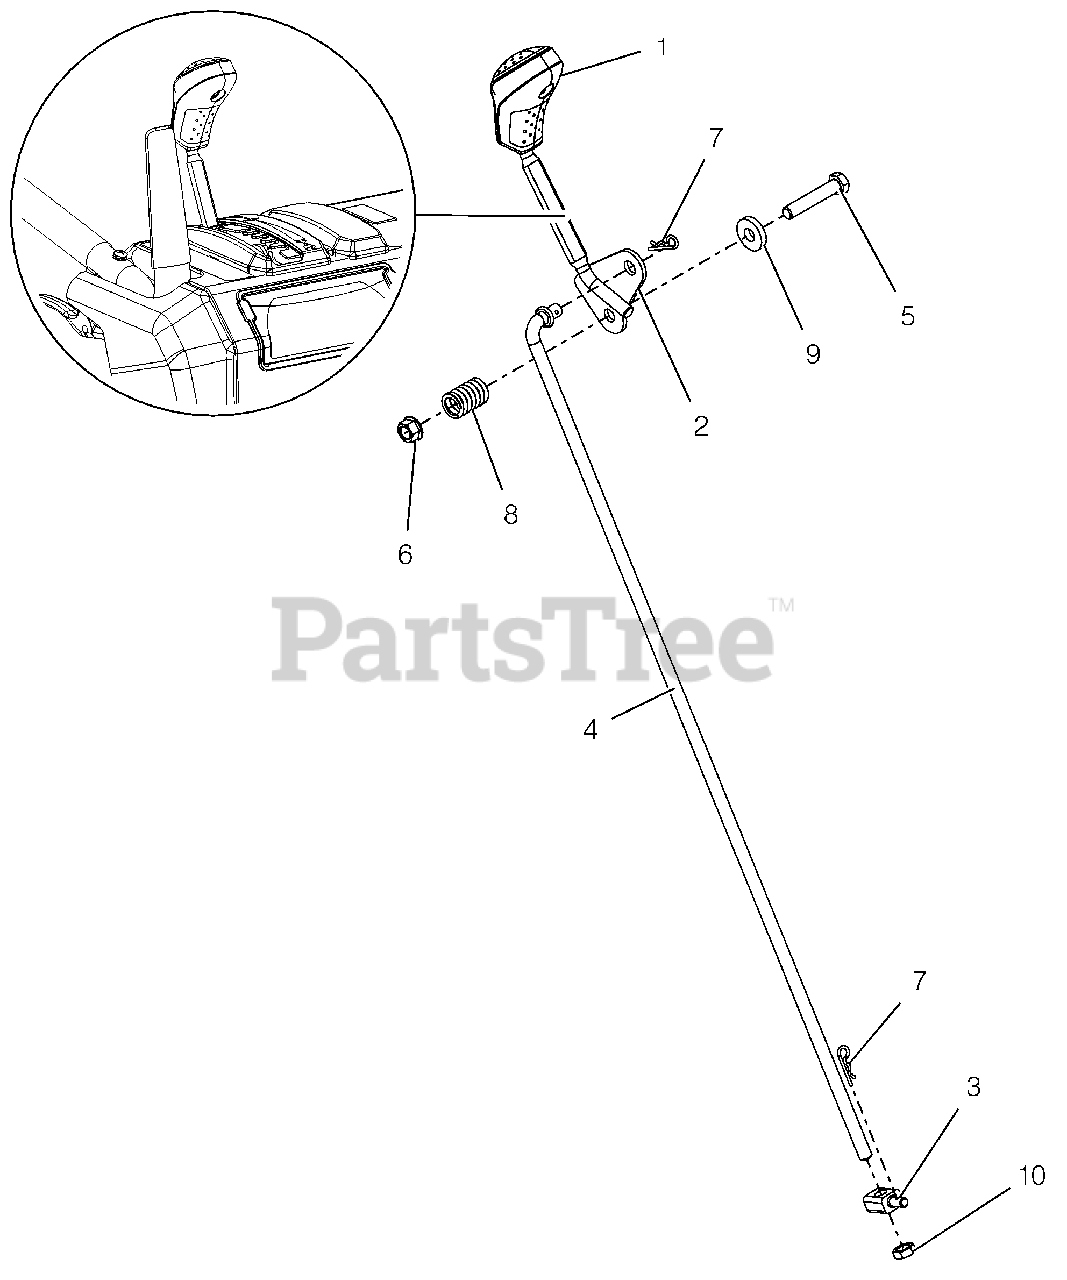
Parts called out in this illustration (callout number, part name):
1	KNOB, CONTROL, DASH
2	WELDMENT,LG DASH SPEED CONTROL
3	PIVOT,SHIFT ROD .375-16(TRUNN)
4	ROD, SHIFT-PRO
5	@BLT-HEX .38-16X2.00 GR5 YWZC
6	@NUT-LK-TOP-FLG .38-16 YWZC
7	PIN-HAIR INT .08X.18X1.18 YWZC
8	SG-COMP .125X.781X1.250
9	WSHR-FL-STL .406X1.00X.188 YWZ
10	NUT-HEX-JAM .375-16 YWZC
